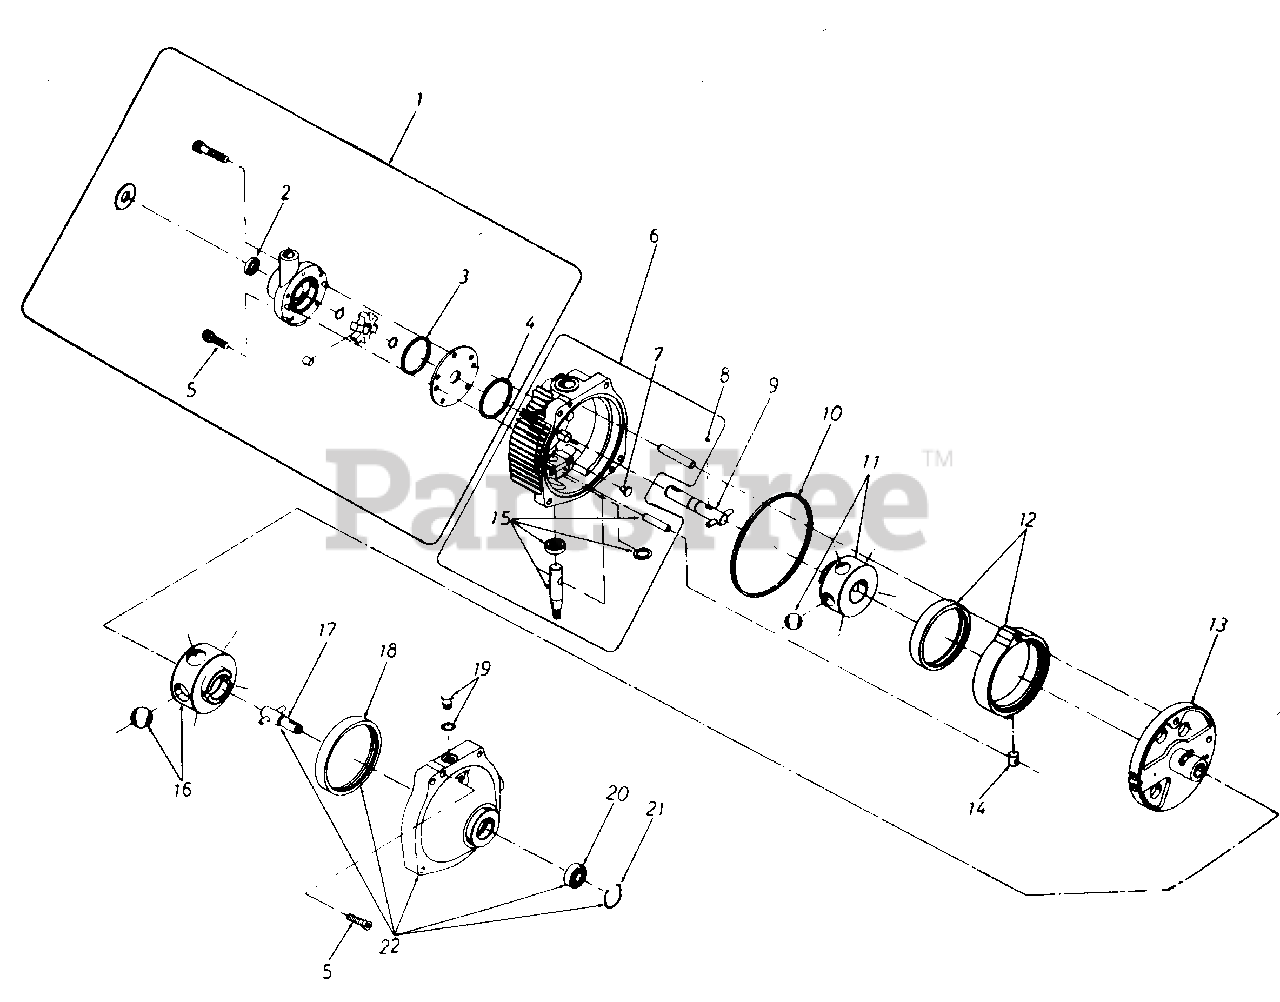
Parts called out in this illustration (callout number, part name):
1	Charge Pump Kit
2	Oil Seal
3	Square Cut Seal Ring .036
4	Square Cut Seal Ring .038
5	Socket Head Cap Screw 5/16-18 x 1.25" Long
6	Cover Subassembly
8	Drive Pin
9	Input Shaft Subassembly
10	Square Cut Seal Ring .166
11	Pump Rotor Ball Subassembly
12	Cam Ring Subassembly
13	Pintle Subassembly
14	Cam Ring Insert
15	Control Shaft Kit
16	Motor Rotor Ball Subassembly
17	Output Shaft Subassembly
18	Motor Race
19	"O"-Ring Plug Subassembly
20	Ball Bearing
21	Retaining Ring
22	Body Subassembly
